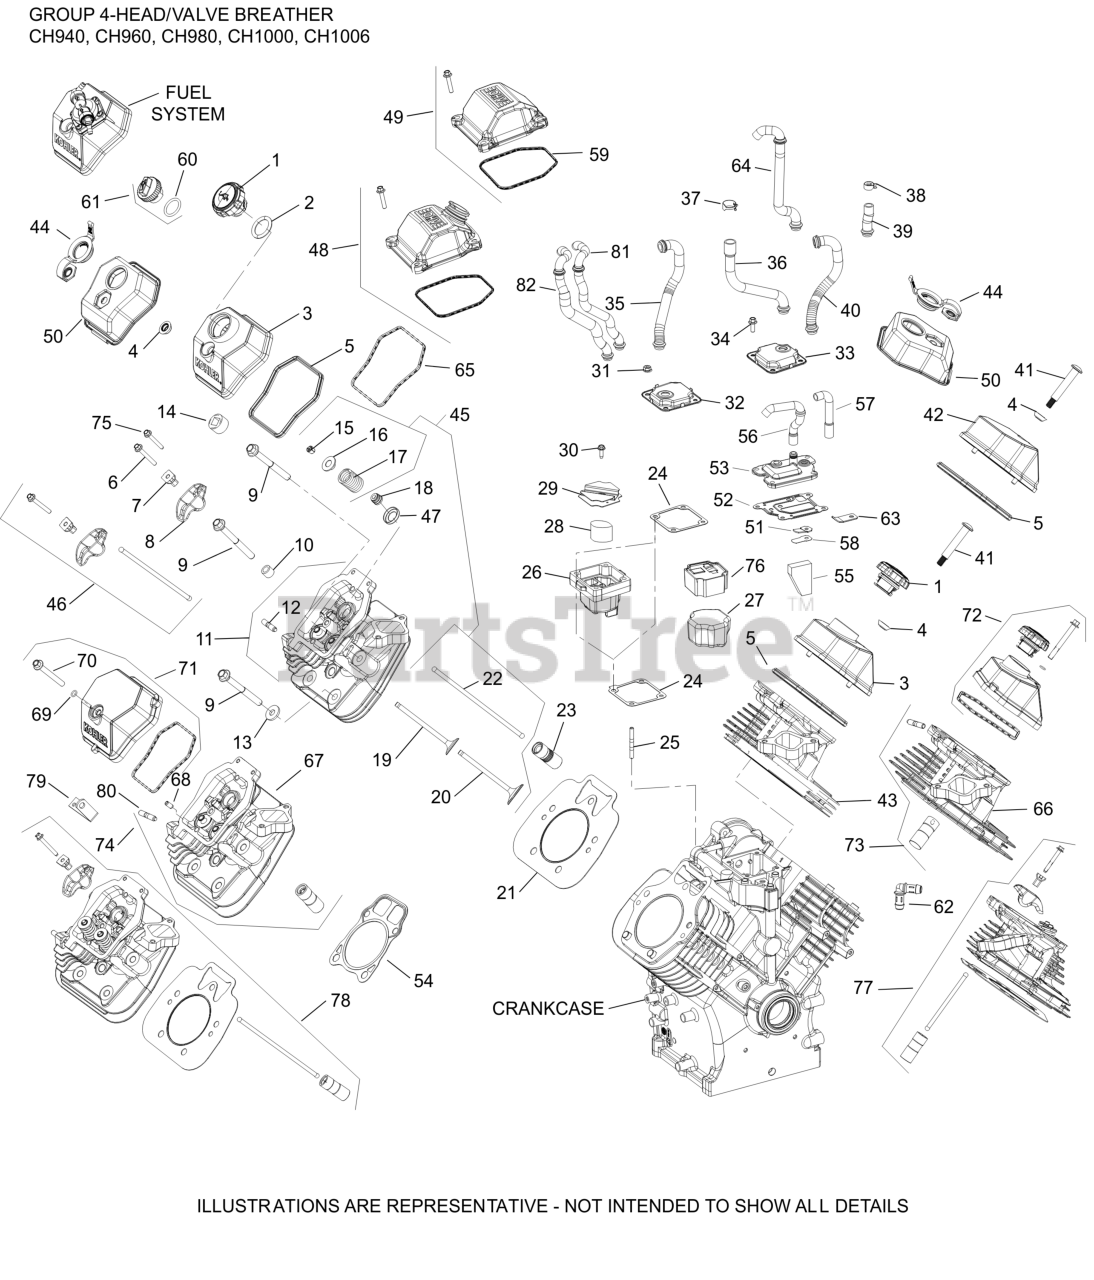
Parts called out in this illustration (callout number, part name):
7	PIVOT, ROCKER ARM
8	ARM, ROCKER
9	SCREW, FLG M10X1.5X90
13	WASHER, FLAT 13/32"
14	PLUG, PIPE 3/4 NPTF SQUARE
15	KIT, RETAINER
16	CAP, VALVE SPRING
17	SPRING, VALVE
18	SEAL, VALVE BAND
19	VALVE, EXHAUST (NITRIDE)
20	VALVE, INTAKE (NITRIDE)
21	KIT, CYLINDER HEAD GASKET
22	ROD, PUSH
23	LIFTER, HYDRAULIC VALVE (SERVICE)
24	GASKET, BREATHER
33	KIT, BREATHER ASSEMBLY
41	SCREW, SHOULDER
44	GROMMET, OIL FILL
50	KIT, VALVE COVER
75	SCREW, HEX FLANGE
76	FILTER, BREATHER
77	KIT, #1 CYLINDER HEAD COMPLETE
78	KIT, #2 CYLINDER HEAD COMPLETE
80	STUD, METRIC EXHAUST
81	HOSE, BREATHER
82	BREATHER ASSEMBLY, HEATED
NI	KIT, #1 CYLINDER HEAD COMPLETE
NI	KIT, #2 CYLINDER HEAD COMPLETE
